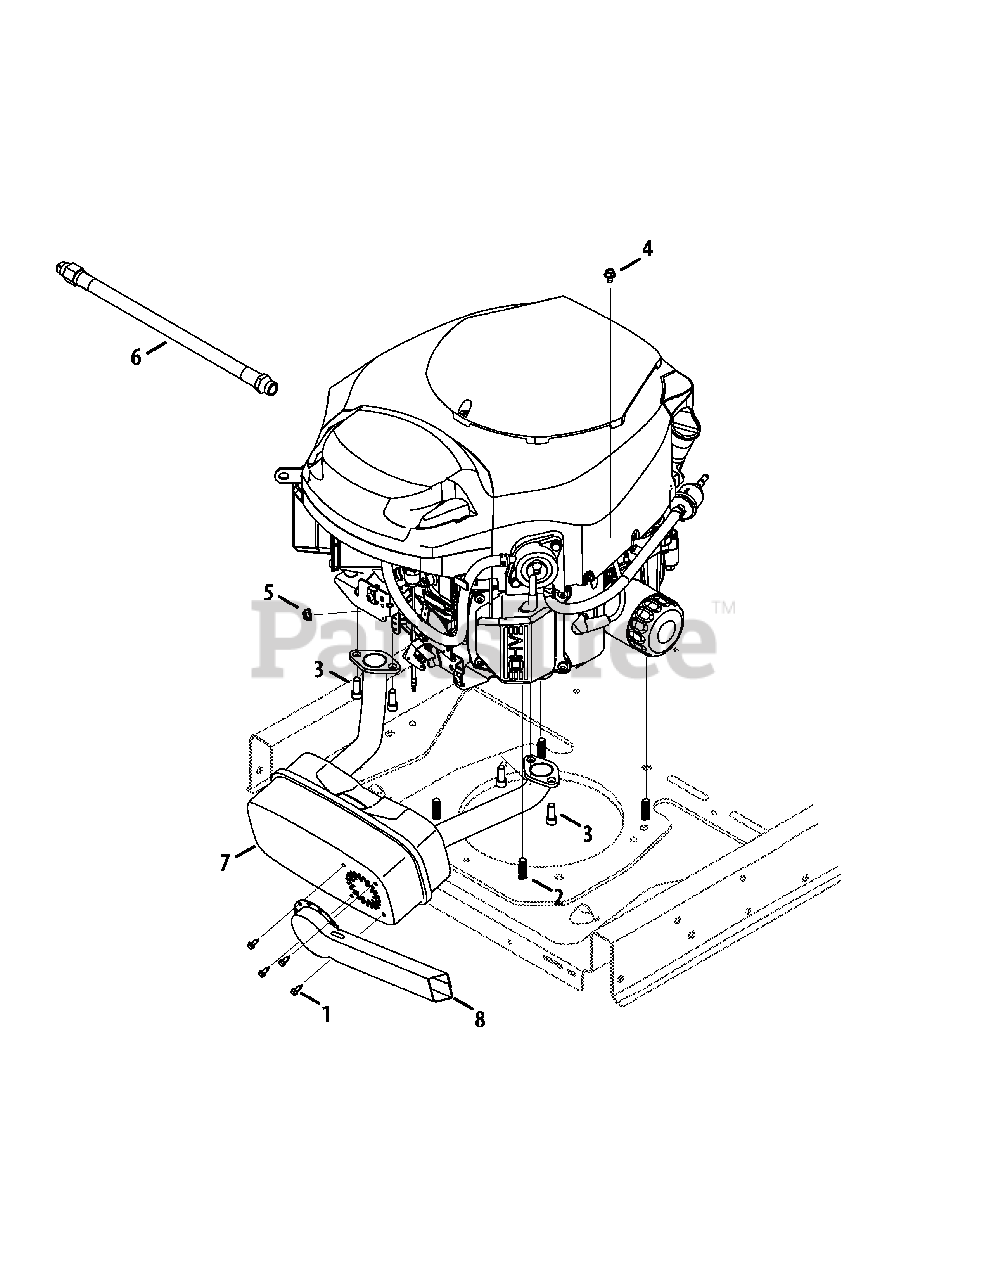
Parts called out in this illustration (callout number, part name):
1	Hex Washer Screw, #8-18 x .500
2	Hex Washer Screw, 3/8-16 x 1.00
3	Socket Head Screw, 5/16-18 x .750
4	Hex Washer Screw, 1/4-20 x .625
5	Flange Lock Nut, 1/4-20
6	Oil Drain Hose
7	Twin Muffler
8	Muffler Deflector Long
